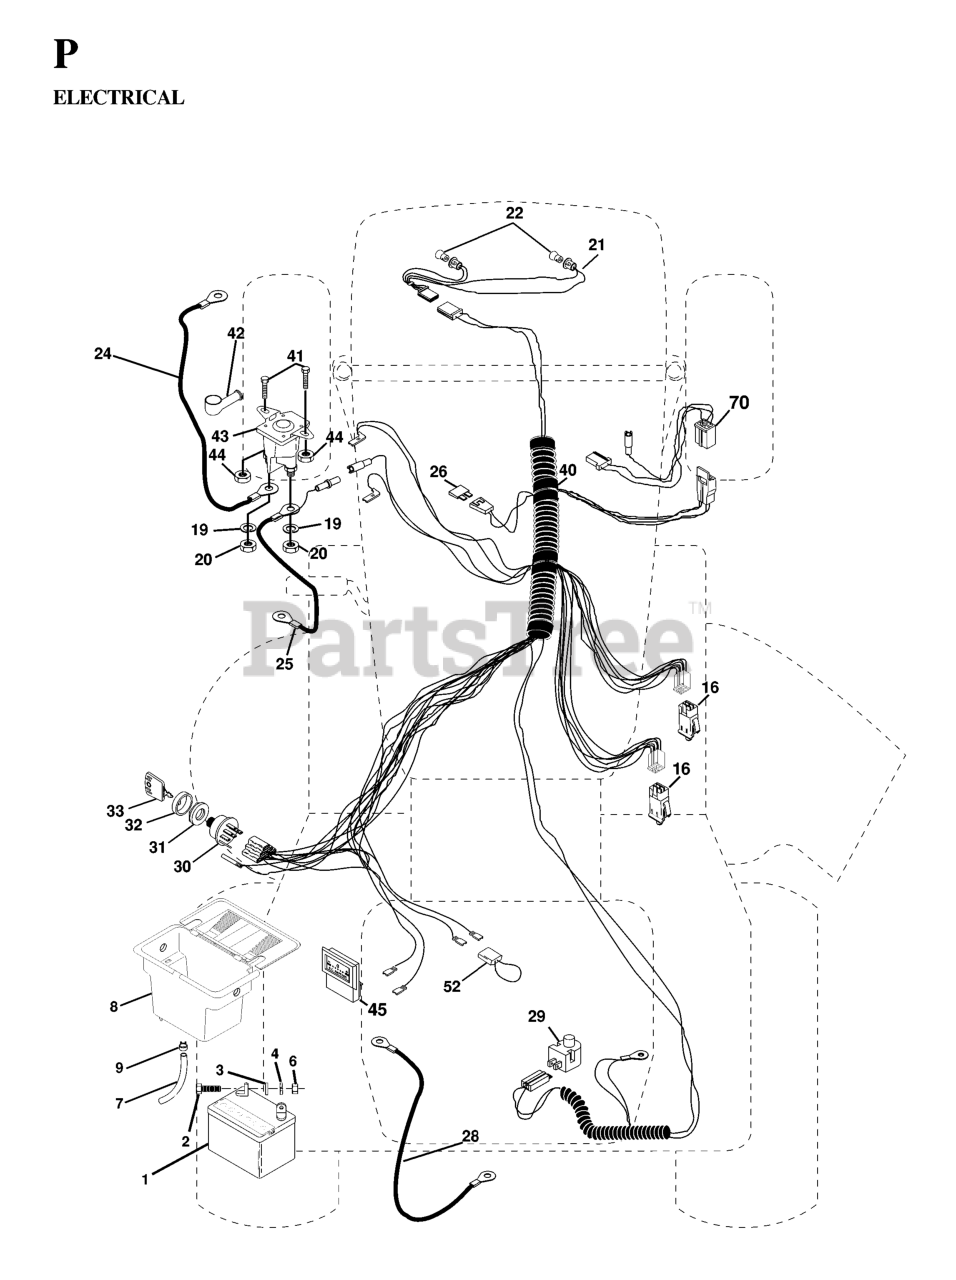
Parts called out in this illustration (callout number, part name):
1	BATTERY.DRY.30.AMP
2	BOLT.HEX.1/4.X.3/4.DICHROMATE
4	LOCKWASHER
6	NUT
7	TUBE BATTERY DRAIN
8	CASE BATTERY MECH HINGE
9	HOSE CLAMP T
16	SWITCH INTERLOCK
19	LOCKWASHER
20	NUT
21	HARNESS LIGHT SOCKET
24	BATTERY CABLE GT
25	CABLE BATTERY
28	CABLE T
29	RP.SWITCH.PLUNGER.NC.GRAY
30	SWITCH.IGNITION.4.POSITION
31	NUT IGNITION
32	COVER SWITCH KEY
33	KEY.MOLDED.GENERIC
40	HARNESS IGN
41	BOLT
42	TERMINAL COVER
43	SOLINOID
44	Nut, Keps Blk Hex 1/4-20 UNC
45	AMMETER
52	WIRE PROTECTION LOOP
70	HARNESS, ENGINE
